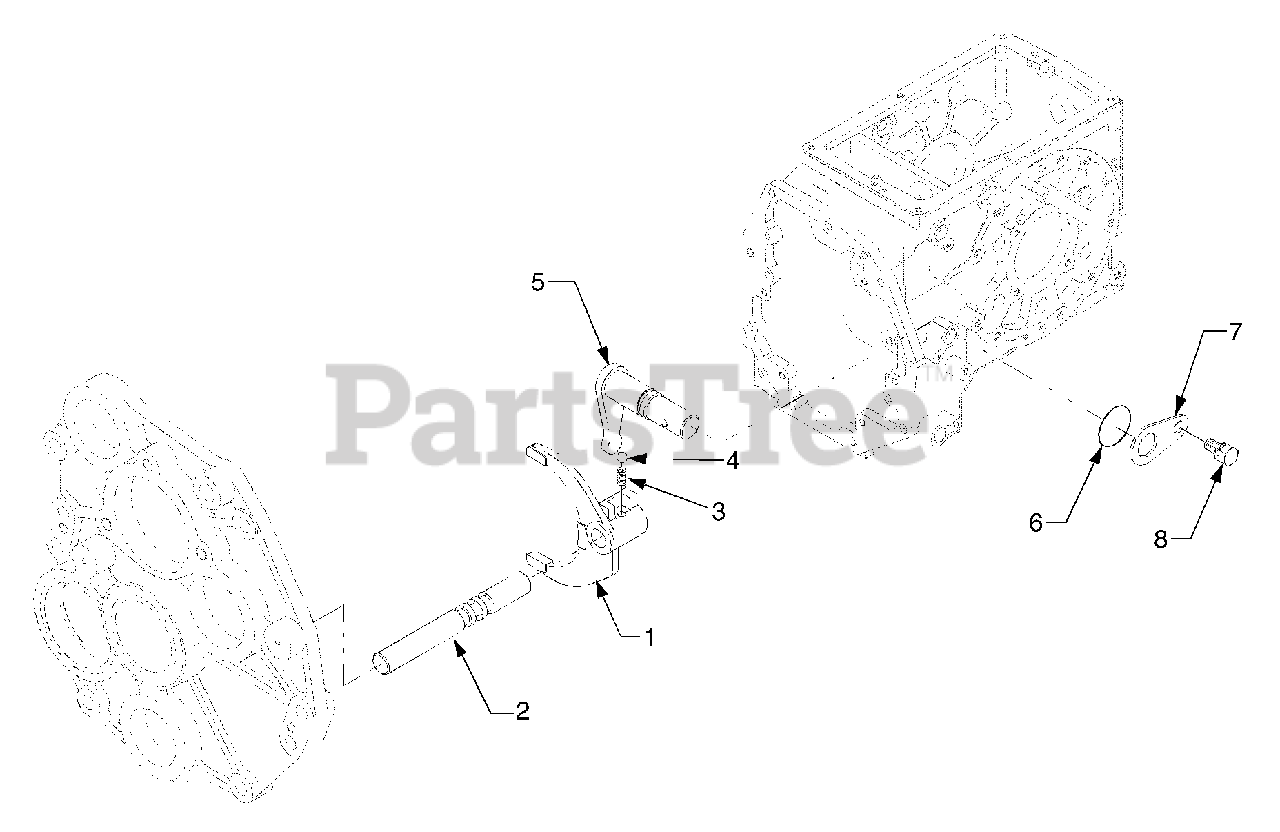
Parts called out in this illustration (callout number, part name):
1	Fork, Shift (Range)
2	Rod, Range Shift
3	Spring, Stopper
5	Arm, Range Shift
